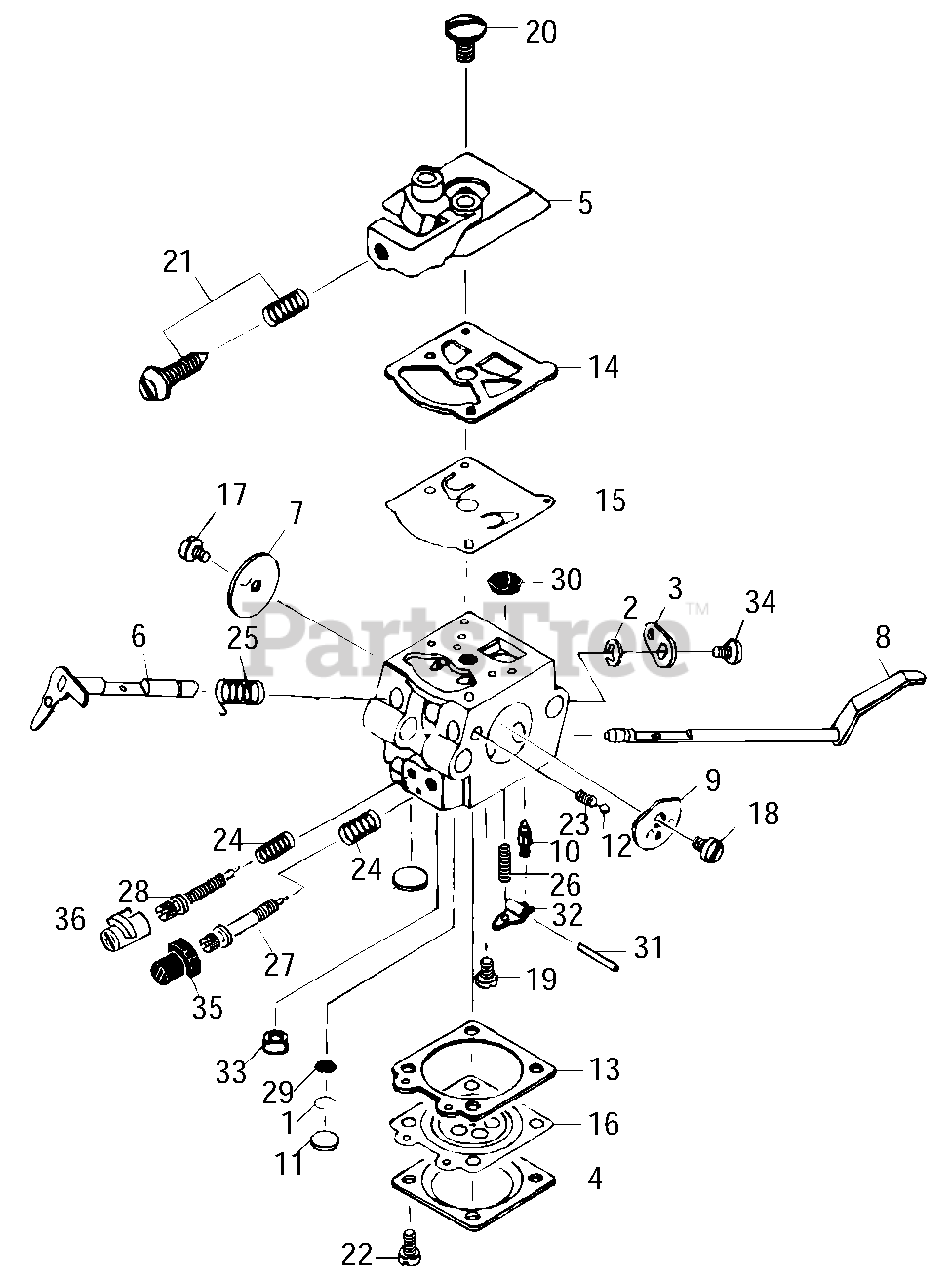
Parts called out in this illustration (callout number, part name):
1	Ring, Screen Retainer
2	Collar
3	Lever, Throttle
4	Cover, Metering Lever
5	Cover, Fuel Pump
6	Shaft Asy, Throttle
7	Valve, Throttle
8	Shaft Asy, Choke
9	Valve, Choke
10	Valve, Inlet Needle
11	Plug, Welch
12	Ball, Choke Friction
13	Gasket, Metering Diaphragm
14	Gasket, Fuel Pump
15	Diaphragm, Fuel Pump
16	Diaphragm Asy, Metering
17	Screw, Valve
18	Screw, Valve
19	Screw, Metering Lever Pin
20	Screw, Pump Cover
21	Screw, Idle Adjust Kit
22	Screw, Metering Cover
23	Spring, Choke Friction
24	Spring Needle
25	Spring, Throttle Return
26	Spring, Metering Lever
27	Needle, High Speed
28	Needle, Low Speed
29	Screen, Check Valve
30	Screen, Fuel Inlet
31	Pin, Metering Lever
32	Lever, Metering
33	Nozzle Asy, Check Valve
34	Screw, Throttle Lever
35	Cap, Limiter, High, Black
36	Cap, Limiter, Low, White
